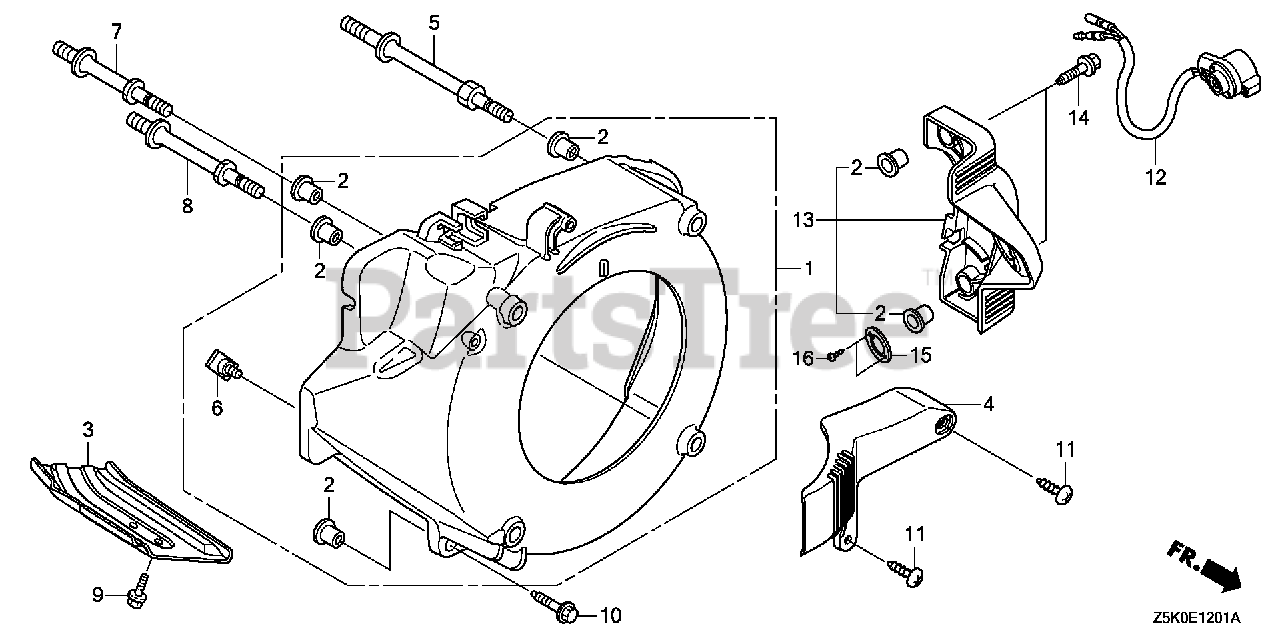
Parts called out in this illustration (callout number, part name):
1	COVER, FAN *NH1* (BLACK)
1	COVER, FAN *R280* (POWER RED)
2	COLLAR, FAN COVER
4	COVER, ELECTRONIC PARTS
5	BOLT, STUD (SEL)
6	BOLT, SPECIAL (6MM)
7	BOLT, STUD
8	BOLT B, STUD
9	BOLT, FLANGE (6X12) (CT200)
10	BOLT, FLANGE (6X25) (CT200)
11	SCREW, TAPPING (5X20)
12	SWITCH ASSY., ENGINE STOP
13	BRACKET, SWITCH
14	BOLT, FLANGE (6X23) (CT200)
15	WASHER, ENGINE STOP SWITCH
16	SCREW, TAPPING (3X10) (NOT AVAILABLE)
